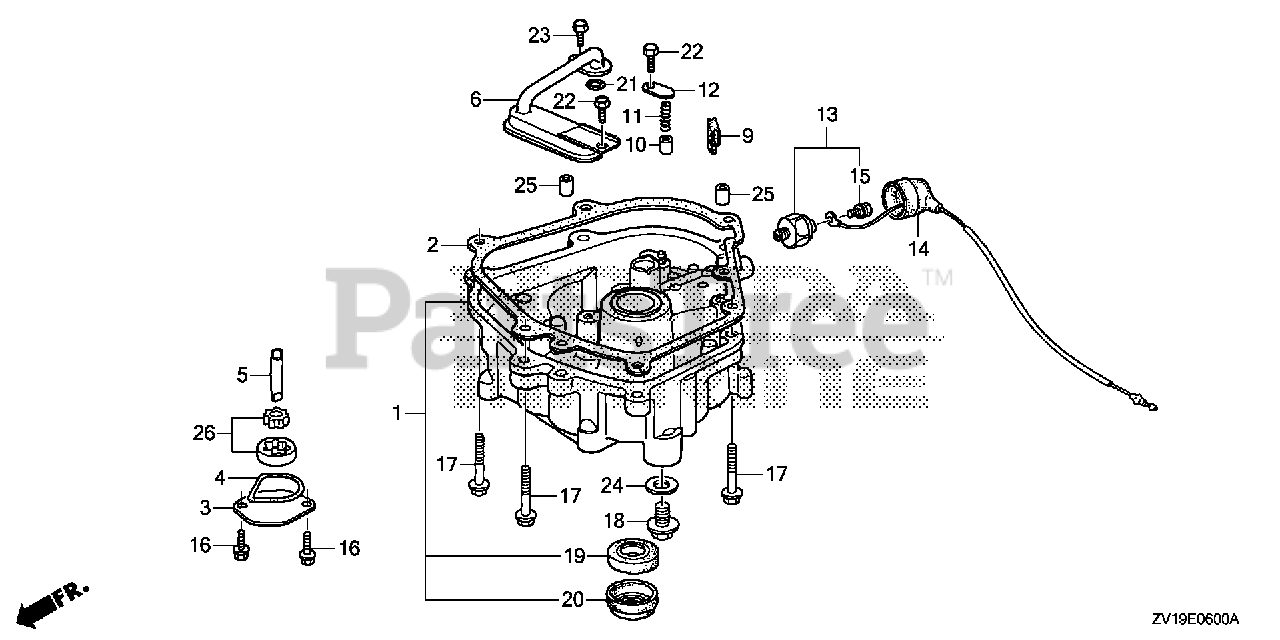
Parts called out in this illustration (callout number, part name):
1	PAN ASSY., OIL (020)
2	GASKET, OIL PAN
3	COVER, OIL PUMP
4	O-RING, PUMP COVER
5	SHAFT, OIL PUMP
6	STRAINER, OIL
7	ROTOR, OIL PUMP (INNER) (YAMADA) (NOT AVAILABLE)
8	ROTOR, OIL PUMP (OUTER) (YAMADA) (NOT AVAILABLE)
9	RUBBER, OIL RETURN
10	VALVE, CHECK
11	SPRING, VALVE
12	PLATE, VALVE
13	SWITCH, OIL PRESSURE
14	WIRE, OIL PRESSURE SWITCH
15	SCREW-WASHER (4X8)
16	BOLT, FLANGE (6X12) (CT200)
17	BOLT, FLANGE (8X32)
18	BOLT, DRAIN PLUG (12X15)
19	OIL SEAL (25X38X7)
19	OIL SEAL (25X38X7) (ARAI)
20	SEAL, COUPLING (25X40X14)
21	O-RING (9.6X2.6) (ARAI)
22	BOLT, HEX. (6X12)
23	BOLT-WASHER (6X14)
24	WASHER, DRAIN PLUG (12MM)
25	PIN A, DOWEL (8X14)
26	ROTOR SET, OIL PUMP
